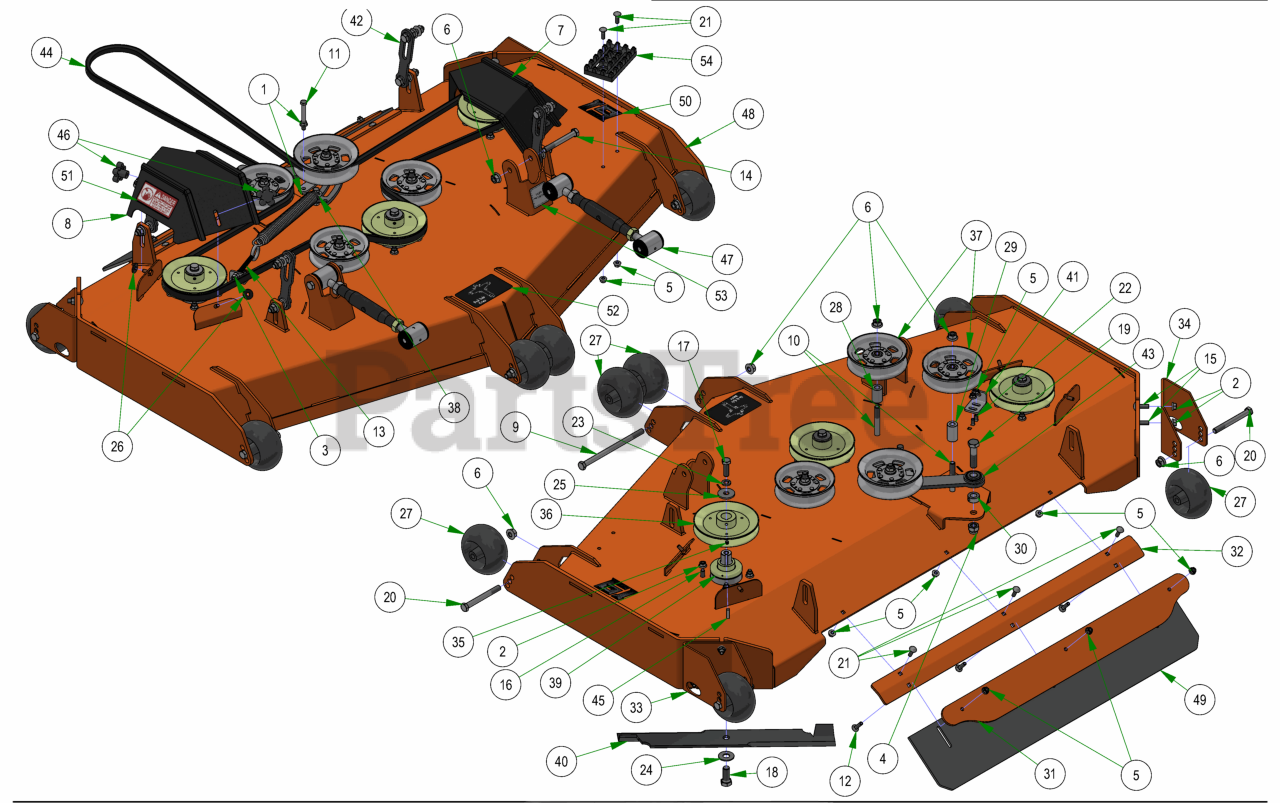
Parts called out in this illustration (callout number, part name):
1	3/8-16 HEX SERRATED FLANGE NUT HARD/ZINC
2	3/8-16 NYLON INSERT FLANGE LOCKNUT (GR.F) ZINC
3	3/8-16 HEX NUT ZINC
4	5/8-11 NYLON INSERT LOCKNUT ZINC
5	5/16-18 NYLON INSERT FLANGE LOCKNUT ZINC
6	1/2-13 NYLON INSERT FLANGE LOCKNUT ZINC
7	2019 61" Outlaw Gen2 Pulley Cover Left
8	2019 61" Outlaw Gen2 Pulley Cover Right
9	1/2-13 X 8 HEX CAP SCREW GR 5 ZINC
10	1/2-13 X 3-1/2 HEX FLANGE BOLT (GR.8) ZINC
11	3/8-16 X 3 HEX CAP SCREW (GR.5) ZINC
12	5/16-18 X 1-1/4 CARRIAGE BOLT ZINC
13	4" 3/8-16 Eye Bolt
14	1/2-13 X 4 HEX CAP SCREW (GR.8) ZINC YELLOW
15	3/8-16 X 1-1/4 CARRIAGE BOLT ZINC
16	3/8-16 X 1-1/2 HEX CAP SCREW (GR.5) ZINC
17	1/2-20 X 1-1/2 HEX CAP SCREW (GR.5) ZINC
18	5/8-18 X 1-1/2 HEX CAP SCREW (GR.8) ZINC YELLOW
19	5/8-11 X 2-1/2 HEX CAP SCREW (GR.5) ZINC
20	1/2-13 X 4-1/2 HEX CAP SCREW (GR.5) ZINC
21	5/16-18 X 1 CARRIAGE BOLT (GR.8) ZINC
22	5/16-18 X 7/8 CARRIAGE BOLT ZINC
23	1/2 SPLIT LOCKWASHER (GR.8) ZINC/YELLOW
24	5/8 USS FLAT WASHER (1-3/4" OD) GR.8 ZINC YELLOW
25	1/2 BELLEVILLE WASHER (1-5/8 OD X .140 THK) ZINC
26	.360 ID X .983 OD X .120 THICK FLAT WASHER NYLON BLACK
27	2019 Deck Wheel
28	.502 ID X .750 OD X 1.500 Long Spacer
29	1 3/4" Pulley Spacer
30	5/8 SOLID SHAFT COLLAR (W/1 SET SCREW) ZINC
31	61 Bolt in Baffle Deck v2 Stripping Plate
32	Rubber Mount Plate - Rear Discharge
33	LH Rear Deck Wheel Bracket - Rear Discharge
34	RH Rear Deck Wheel Bracket - Rear Discharge
35	5/16-24 X 1/4 SOCKET SET SCREW (CUP PT) PLAIN
36	6 1/4" Drive Pulley
37	5-3/4 Idler Pulley
38	2019 Outlaw Gen2 Deck Spring
39	OUTLAW SPINDLE ASSEMBLY
40	61" High Lift Fusion Blade
41	2019 Deck Eye Bolt Tab
42	Deck Hanger Assembly
43	2019 Rebel Rogue Deck Idler
45	1/4 X 1 SQ MACHINERY KEY 1018 STL PLN
46	5/16" Knob
47	Turnbuckle Assembly (M20-2.5)
48	61 Rear Discharge Deck
49	R Series Rubber For Deck
50	61" Deck Decal
51	Danger Decal-Spindle/Discharge
52	2019 Rebel & Rogue Deck Belt Route Decal
53	Deck Impact Patent Decal 9591803
54	Deck Step Assembly
